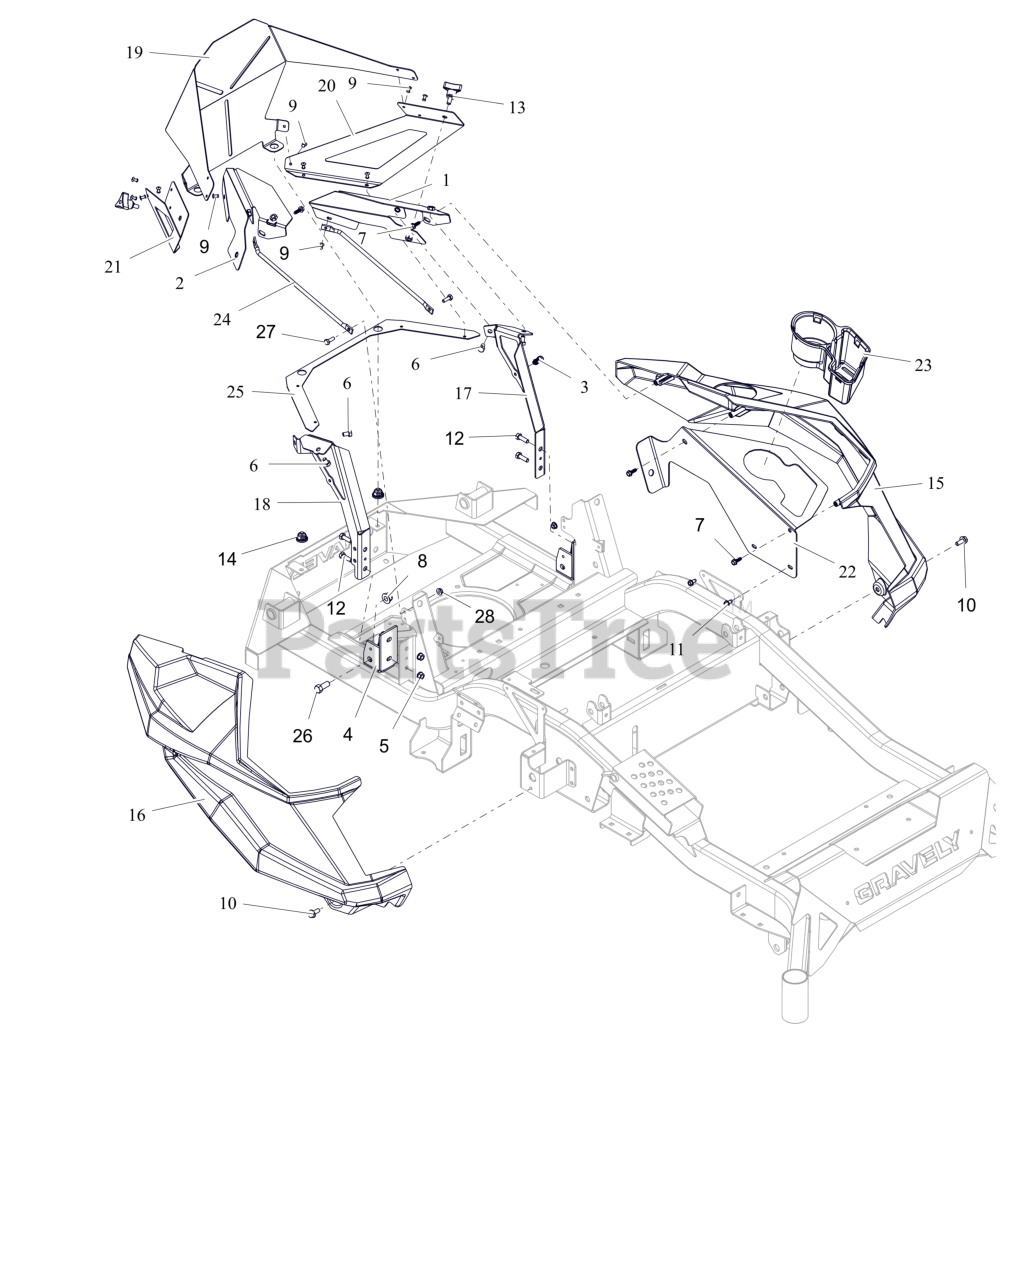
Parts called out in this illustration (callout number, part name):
1	PANEL, LH (RED)
2	PANEL, RH (RED)
3	CLIP, CABLE GUIDE
4	BRKT, ROPS SUPPORT
5	NUT,LK-CTR-FLG .31-18 GF ZCC
6	BLT, HEX .31-18X.50 GR5 ZCC
7	SCR, PLASTITE-HWH 0.25 X 0.75 ZC120
8	NUT,NYL-FLG .44-14 GF ZCC
9	RIVET, #66 STEEL POP PD BLACK
10	BLT, SERHFWH 0.312-18X0.75 GR5 ZCC
11	SCR-TAP .25-20X.50 HWH ZCC
12	BLT, HEX .31-18X1.00 G8 ZCC
13	KNOB,WING STUD 5/16-18 X .75
14	GROMMET, 10MM BOLLHOFF
15	FENDER, LH
16	FENDER, RH
17	BRKT, LH FENDER MTG (RED)
18	BRKT, RH FENDER MTG (RED)
19	WRAP, REAR (BLACK)
20	WRAP, REAR - LH (RED)
21	WRAP, REAR - RH (RED)
22	PANEL, HD CUPHOLDER (RED)
23	HOLDER, CUP
24	ROD, STIFFENER
25	STIFFENER, BACK WRAP (RED)
26	BLT, HEX 0.4375-14X1 GR5 ZCC
27	BLT, HEX .25-20X.75 G5 ZCC
28	NUT-LK-CTR-FLG .25-20 ZC120
